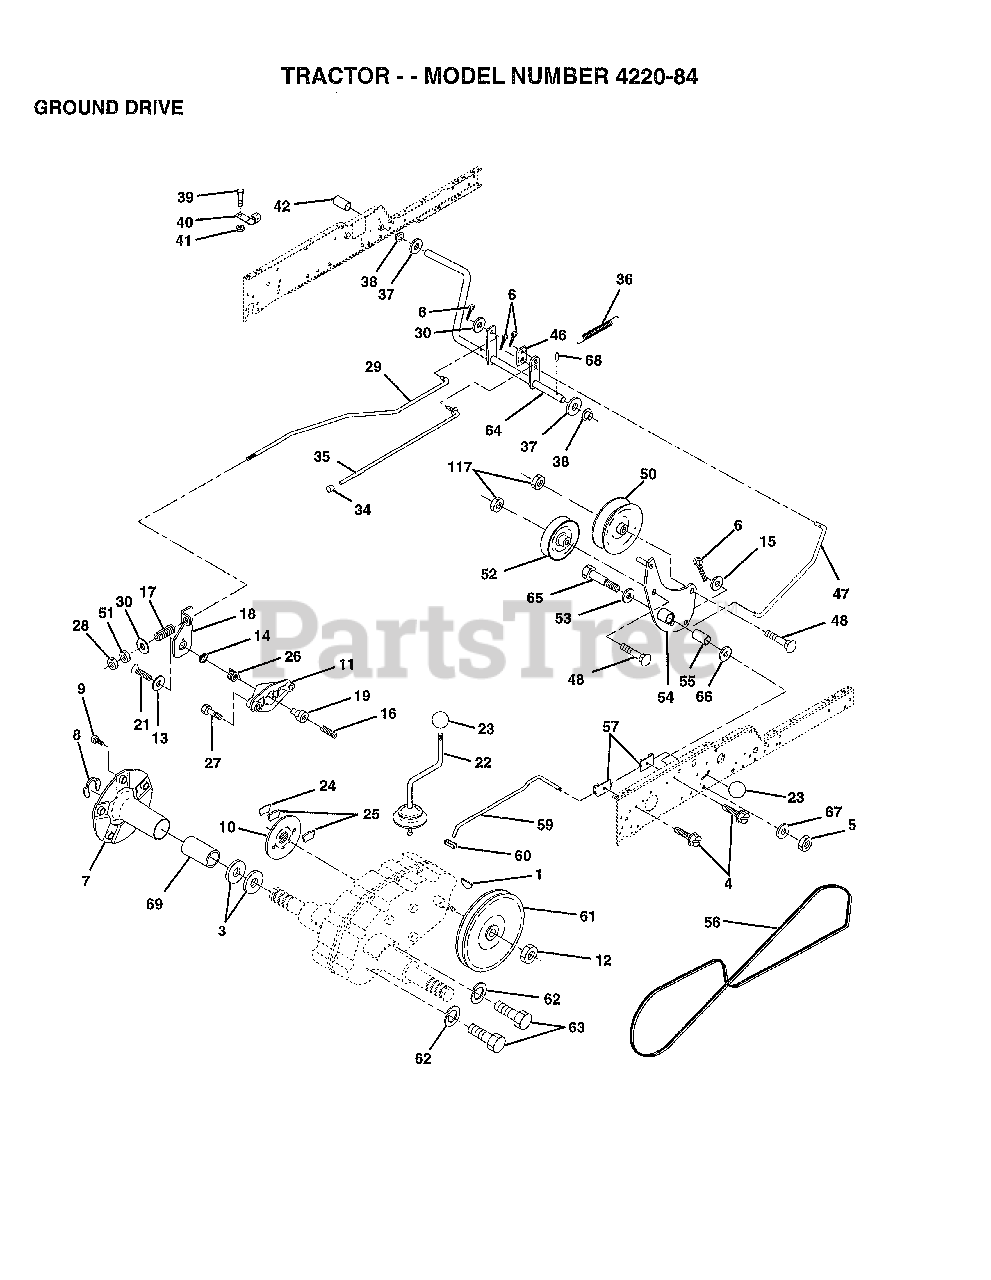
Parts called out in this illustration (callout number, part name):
3	WASHER T
6	COTTER PIN
9	BOLT.HUB.WHL.REAR
10	BRAKE.DISC.
11	YOKE BRAKE DISC
12	"LOCKNUT,1/2-20UNF"
13	WASHER SPECIAL
14	BUSHING LEVER BKT
15	WASHER
16	SCREW SET 1/4-20
17	"SPRING,ROD BRAKE"
18	LEVER BRAKE
19	CAM BRAKE DISC GT
21	SCREW FLT 1/4X28
22	GEAR SHFT LVR T
23	KNOB
24	SUPPORT PUCK BRKE
25	PUCK BRAKE TOP
26	SPRING RET BRAKE
27	SCREW HX WASH
28	NUT
30	WASHER HYT
34	PLUNGER CAP T
35	ROD BRAKE PART GT
36	SPRING.GRND.DRIVE
38	BUSHING.NYLINER
39	SCREW
40	ACT-SWITCH T
42	PEDAL COVER T
46	RETAINER.SPRING
47	ROD.CLUTCH
48	BOLT.3/8-16X1.50
50	FLAT IDLER PULLEY
52	PULLEY.IDLER.V.GR
53	WASHER T
54	CLUTCH.ARM.ASM
55	"LY, BEARING"
56	BELTV.GR.DR.83.
57	BRACKET.ROD.SHIFT
59	ROD SHIFT HI LO
60	CONNECTING LINK
62	LOCKWASHER
63	BOLT
64	SHAFT-BRAKE/CLUTC
65	AXLE BOLT
66	WASHER.HARD.BLADE
67	WASHER
68	ROLL PIN STD
69	"COVER, HUB"
